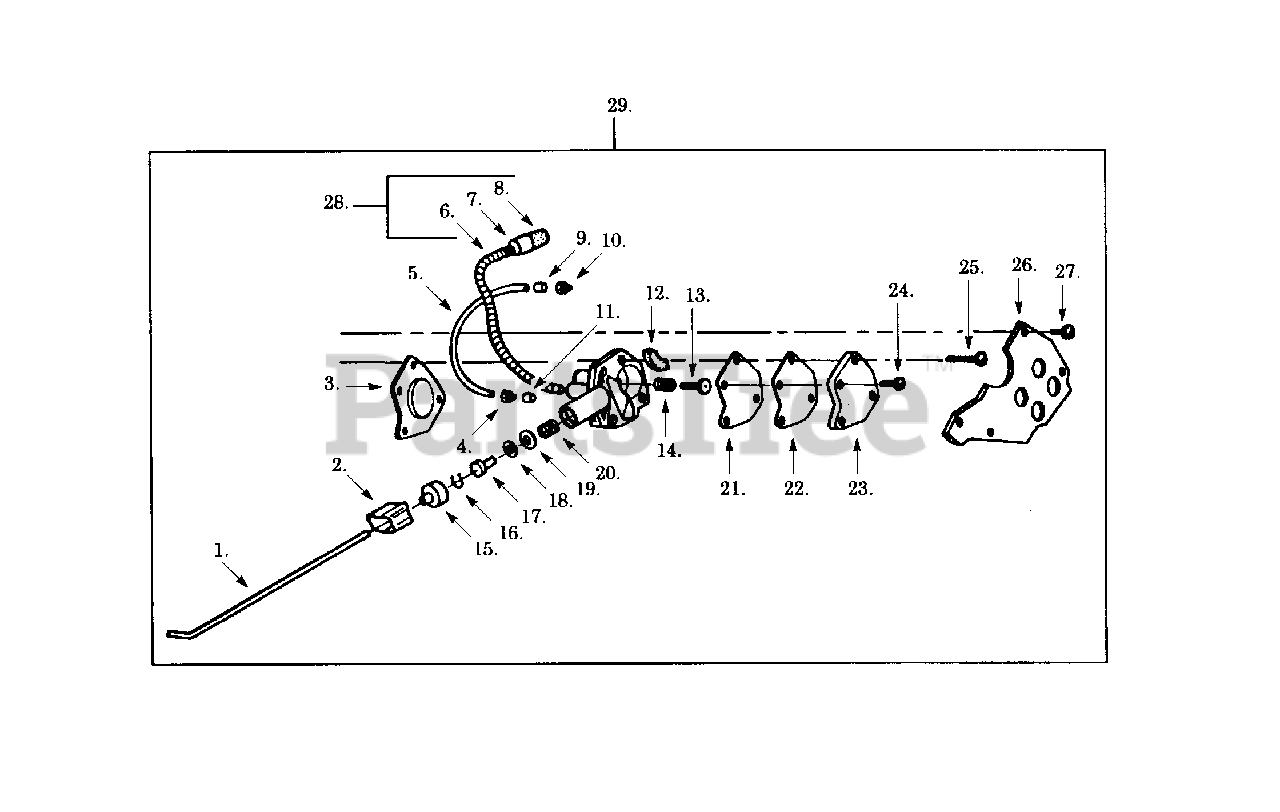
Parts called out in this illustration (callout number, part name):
1	Manual Oiler Rod
2	Oiler Rod Boot
3	Gasket
4	Tubing Nut
5	Oil Line Discharge (Bulk 530-008115)
6	Oil Line Protector Spring
7	Oil Line (Bulk 530-008132)
8	Oil Line Pick-up Weight
9	Sleeve-1/8 Tubing
10	Slotted Tubing Nut
11	Tubing Nut
12	Oil Pump Vent Foam
13	Button & Pintle Ass'y
14	Diaphragm Spring
15	Oil Pump Cap
16	Retainer Ring
18	O-Ring-Quad Ring
21	Diaphragm
22	Gasket
23	Pump Cover
26	Oiler Cover Plate
28	Oil Pick-up Ass'y.
29	Oil Pump Ass'y. Kit
